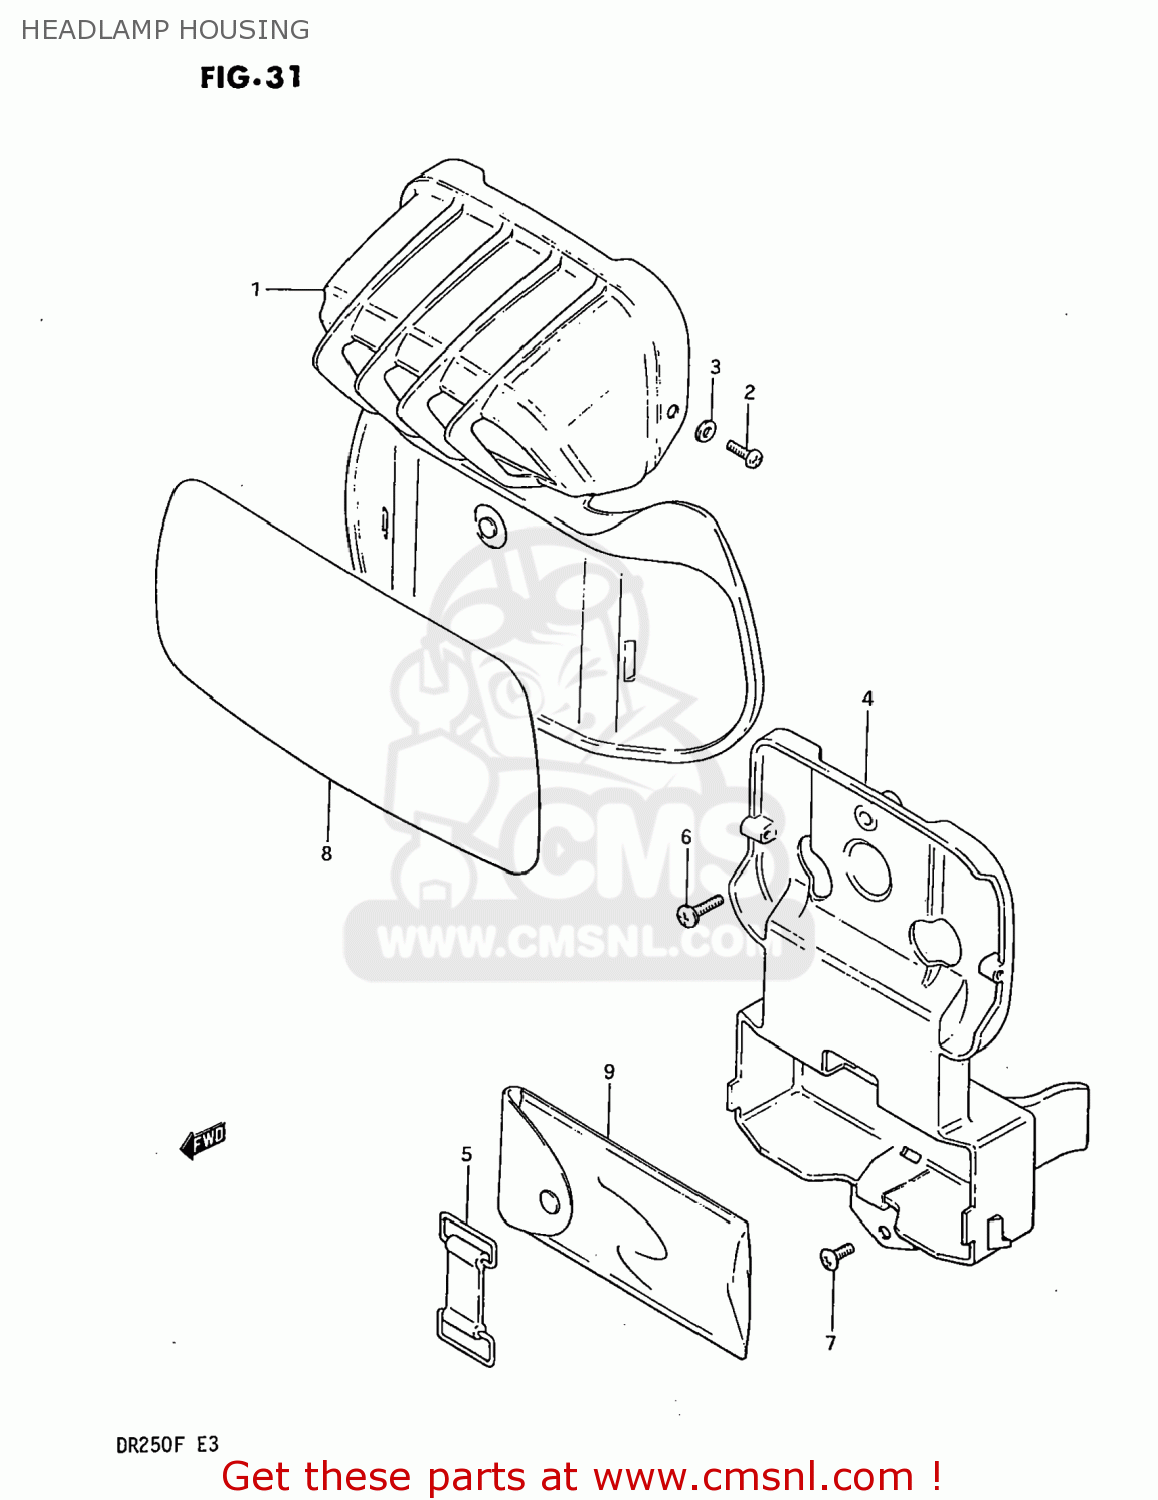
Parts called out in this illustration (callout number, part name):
1	HOUSING,HEADLAMP
2	TAPPING SCREW
3	WASHER 4MM
4	HOLDER,TOOL
5	BAND
6	SCREW
7	SCREW
8	EMBLEM,FRONT NUMBER PLATE
9	TOOL ASSY
